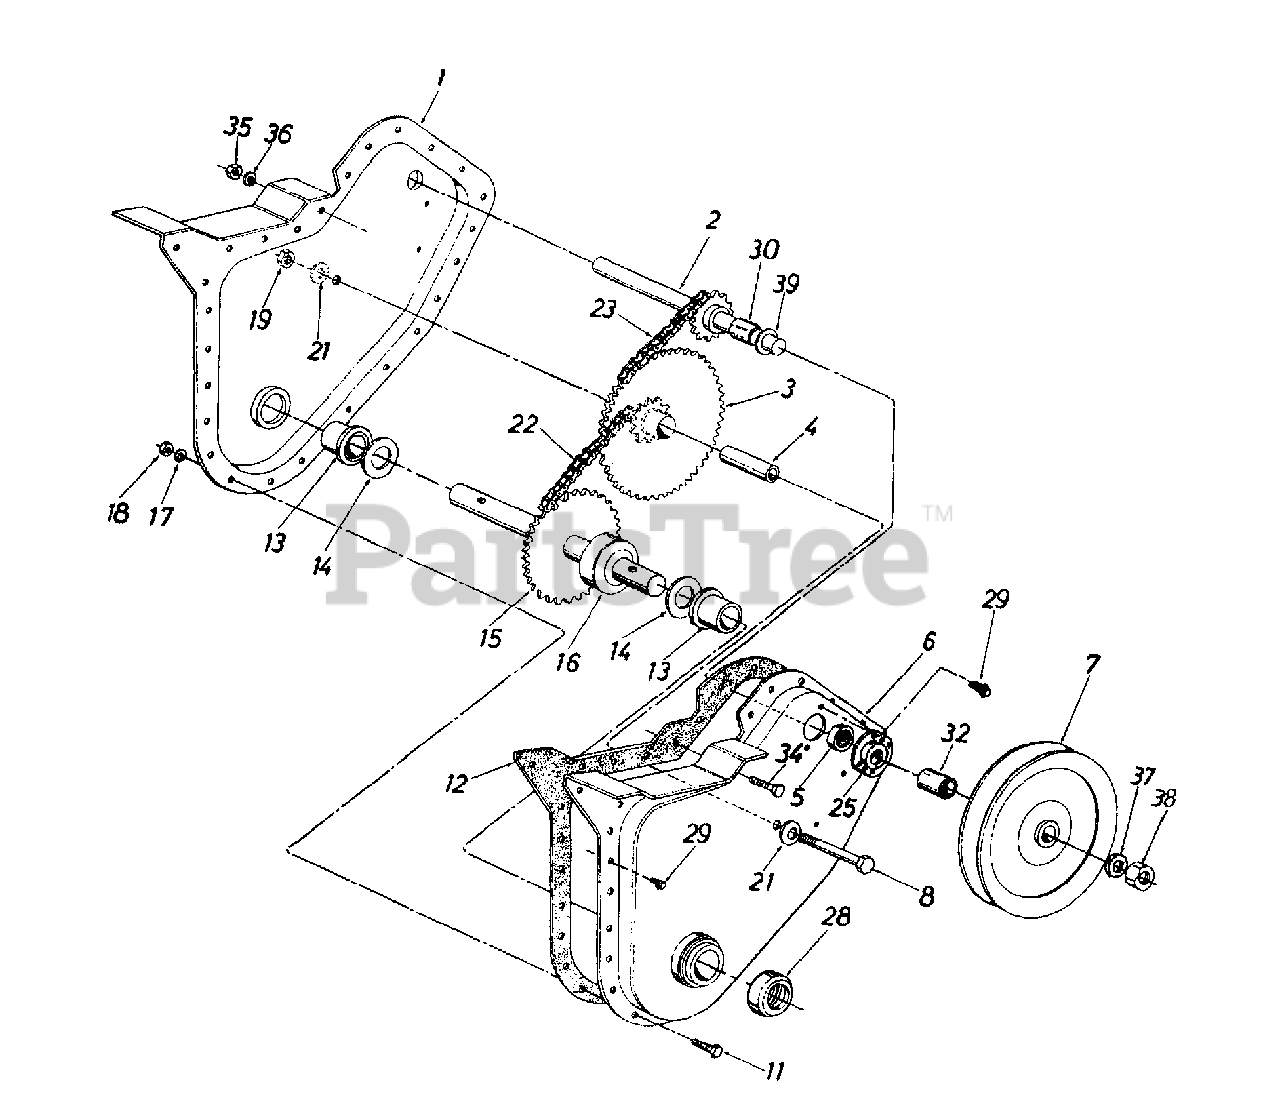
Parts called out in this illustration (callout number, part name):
3	Hub and Sprocket Ass'y.
4	Bearing Inner Race
5	Ball Bearing
8	Hex Bolt 3/8-24 x 2.5"
11	Hex Bolt 1/4-28 x .625"
12	Gasket
13	Flange Brg. .879" I.D.
14	Fl-Wash. .88" I.D. x 1.5"
15	Tine Shaft Ass'y.
16	Spacer 7/8" I.D.
17	L-Wash. 1/4" I.D.
18	Hex Nut 1/4-28 Thd.
19	Hex Ins. L-Nut 3/8-24 Thd.
21	Bell-Wash. .406" I.D.
22	Chain #420 1/2" Pitch 38 Links
23	Chain #35 .375" Pitch 50 Links
25	Bearing Housing
28	Shaft Seal
29	Hex Wash. Hd. Self-Tap Scr.
30	Spacer.63" I.D. x .77" O.D. x .38"
32	Spacer.647 x .77"
34	Hex Bolt 5/16-18 x .75" Lg.
35	Hex Nut 5/16-18 Thd.
36	L-Wash. 5/16" I.D.
37	Bell-Wash. .38" I.D. x .88" O.D.
38	Hex Flange L-Nut 3/8-24 Thd.
39	Washer.652 I.D.
